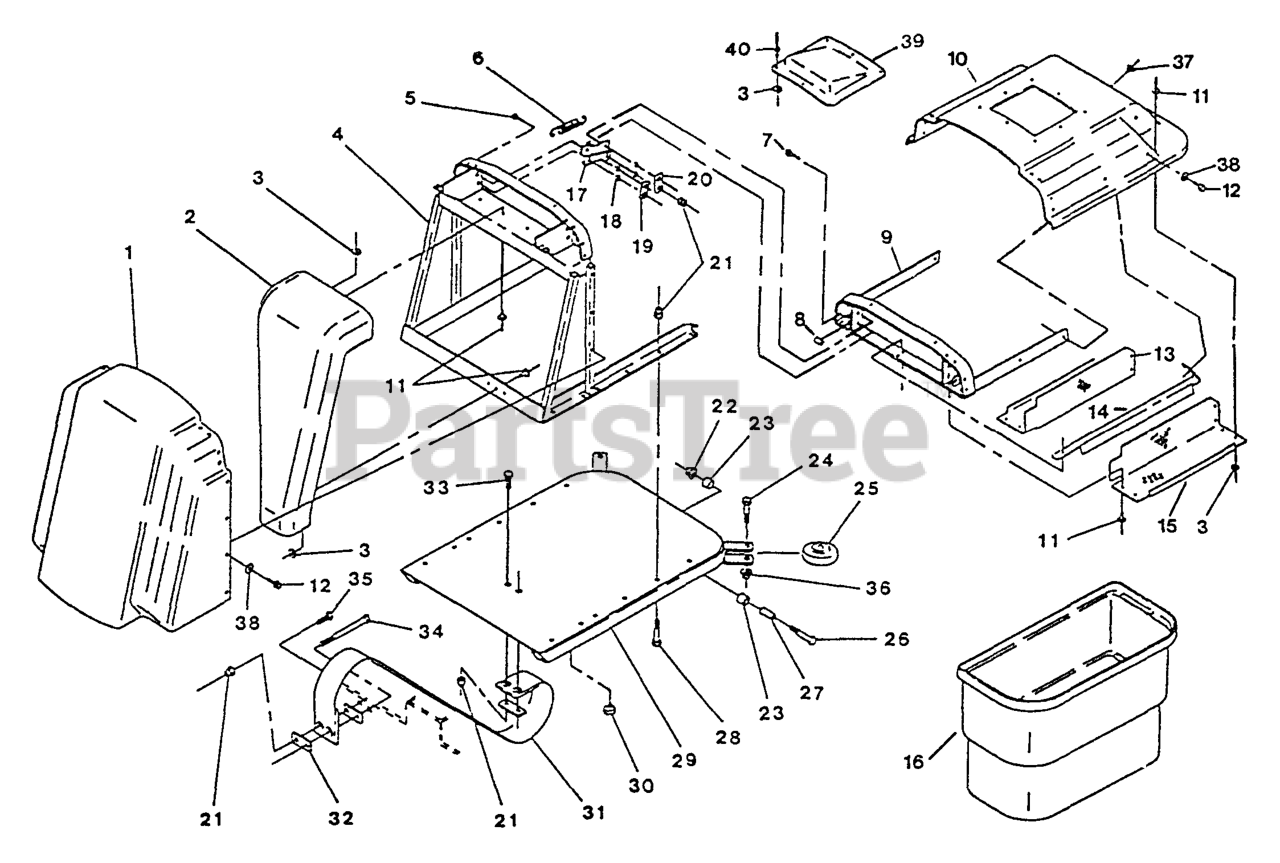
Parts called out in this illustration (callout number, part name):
6	SPRING,CATCHER LID
8	BUSHING,LID SPRING
10	TOP,GRASS CATCHER
13	SCREEN,PERFORATED RH PNT
15	SCREEN,PERFORATED LH PNT
17	LINK,HINGE PLTD
23	SLEEVE-BEARING
25	WHEEL,RUBBER
27	BUSHING,BOX PIVOT
31	STRAP,BOX RESTRAINT
32	CLAMP,STRAP
33	Bolt, Carriage 1/4-20 X 1
37	Rivet, 3/16 X 1/4
39	WINDOW,GRASS CATCHER
